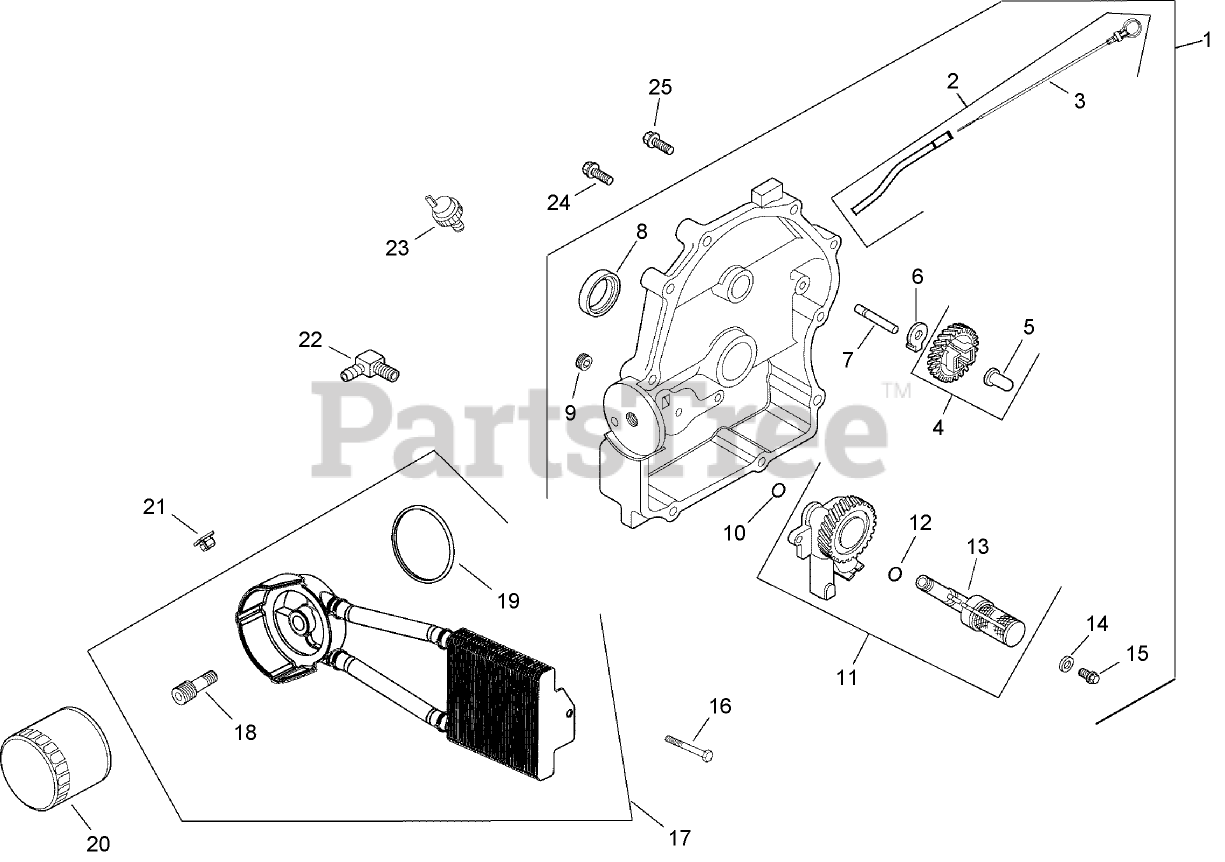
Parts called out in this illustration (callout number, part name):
1	Closure Plate ASM
2	DIPSTICK AND DIPSTICK TUBE ASM
3	Dipstick
4	GOVERNOR GEAR W/PIN KIT
5	PIN-REGULATING, GOVERNOR
6	TAB-LOCKING
7	SHAFT-GEAR, GOVERNOR
8	SEAL-OIL (P-T-O END)
9	PLUG-PIPE, COUNTERSUNK (1/8)
10	O-Ring
11	Oil pump ASM (Incl. Ref. #12 and 13)
12	O-RING
13	TUBE-PICK UP, OIL
14	WASHER-FLAT (6 MM)
15	SCREW-FLANGE, THREAD FORMING (M6X1.0X25)
16	SCREW-TAPPING
17	Kit, alum base oil cooler (Incl. Ref. #16-18, 20 and 22)
18	Nipple-Filter, Oil
19	O-Ring
20	Filter-Oil
21	Nut-Plastic
22	Connector-Hose, 90 Deg
23	SWITCH-PRESSURE, OIL
24	Screw-HF (M8x1.25x45)
25	SCREW-FLANGE (M8X1.25X45)
